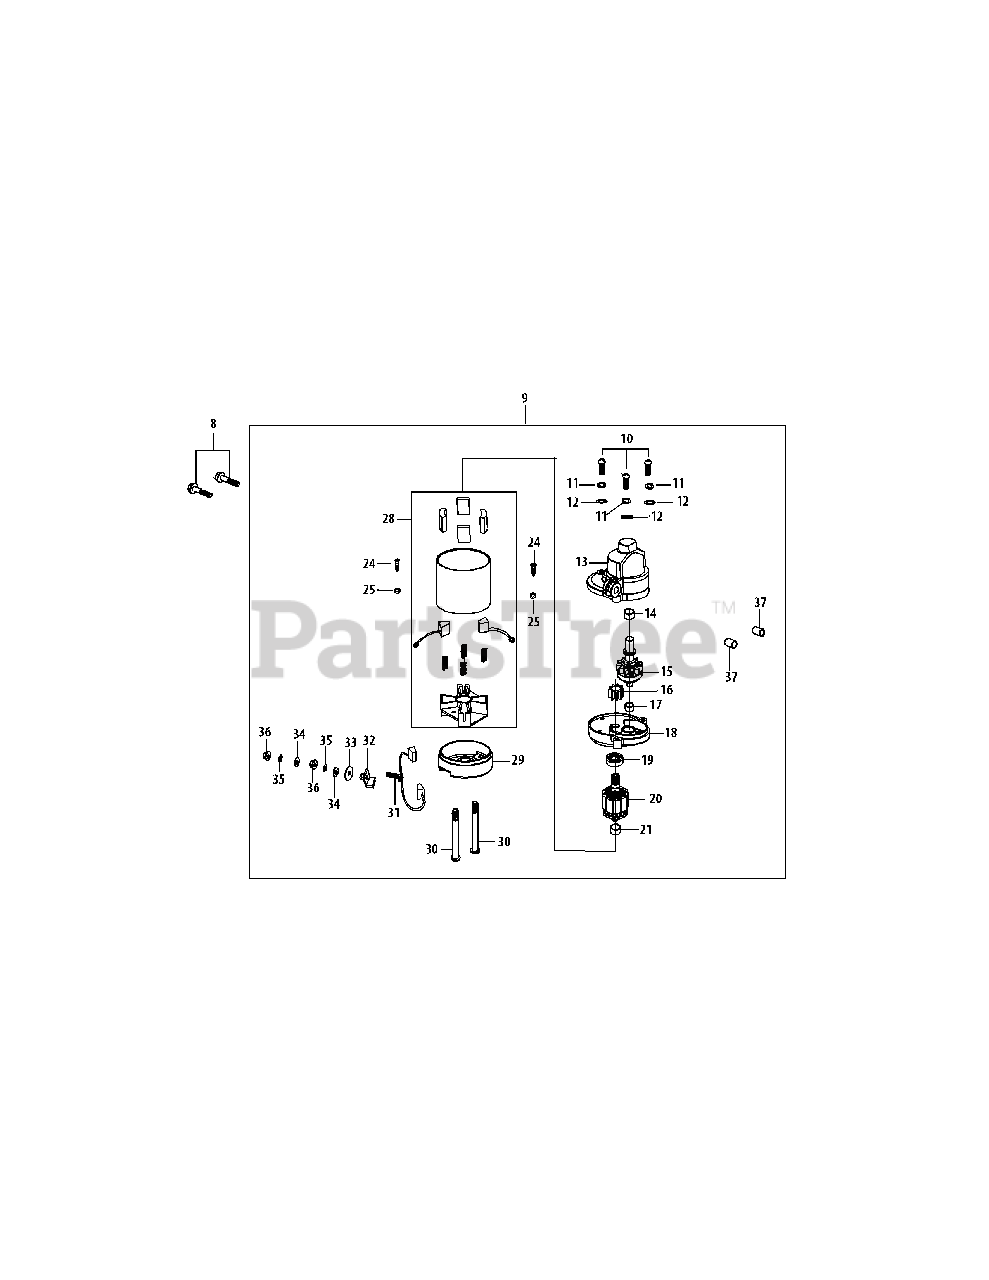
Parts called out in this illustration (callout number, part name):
8	Bolt M8×40
9	Starter Assembly
10	Screw M5×25
11	Lock Washer 5
12	Plain Washer
13	Starter Drive End Cover
15	Starter Pinion/Clucth Assembly
18	Clutch Pinion Cover
19	Bearing 6001Zz
20	Starter Armature
24	Self-Tapping Bolt
25	Lock Washer
28	Brush Assembly
29	Starter End Cover
30	Bolt M6×100
31	Bolt M6×30
32	Waterproof Starter Washer
33	Insulation Washer
35	Lock Washer 6
36	Nut M6
37	Dowel Pin 10×14
